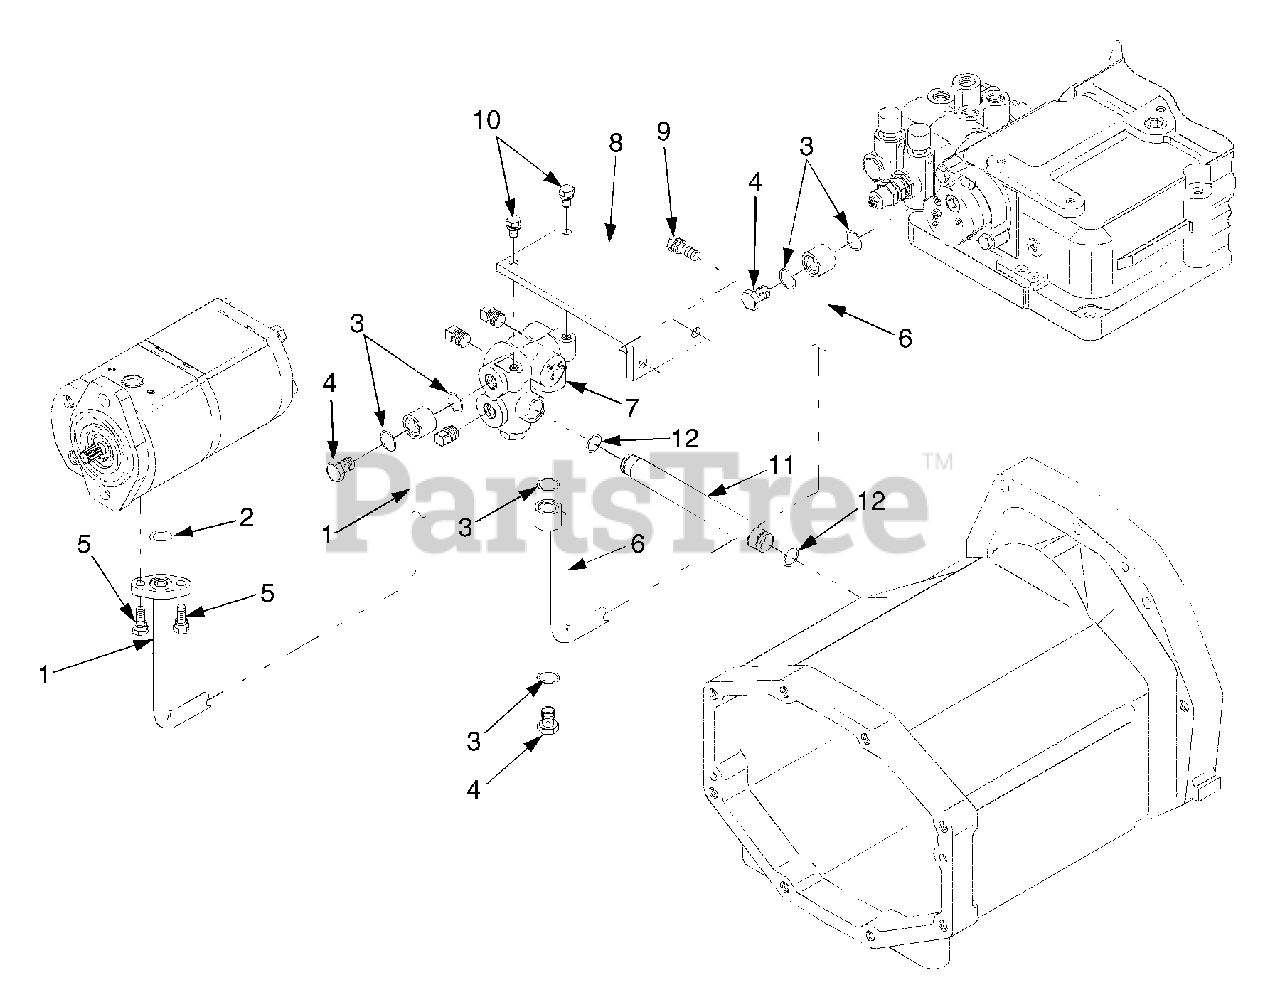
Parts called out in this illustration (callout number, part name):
1	Pipe 1, Hydraulic
6	Pipe 2, Hydraulic
7	Hydraulic Block Ass'y
8	Support, Hydraulic Block
